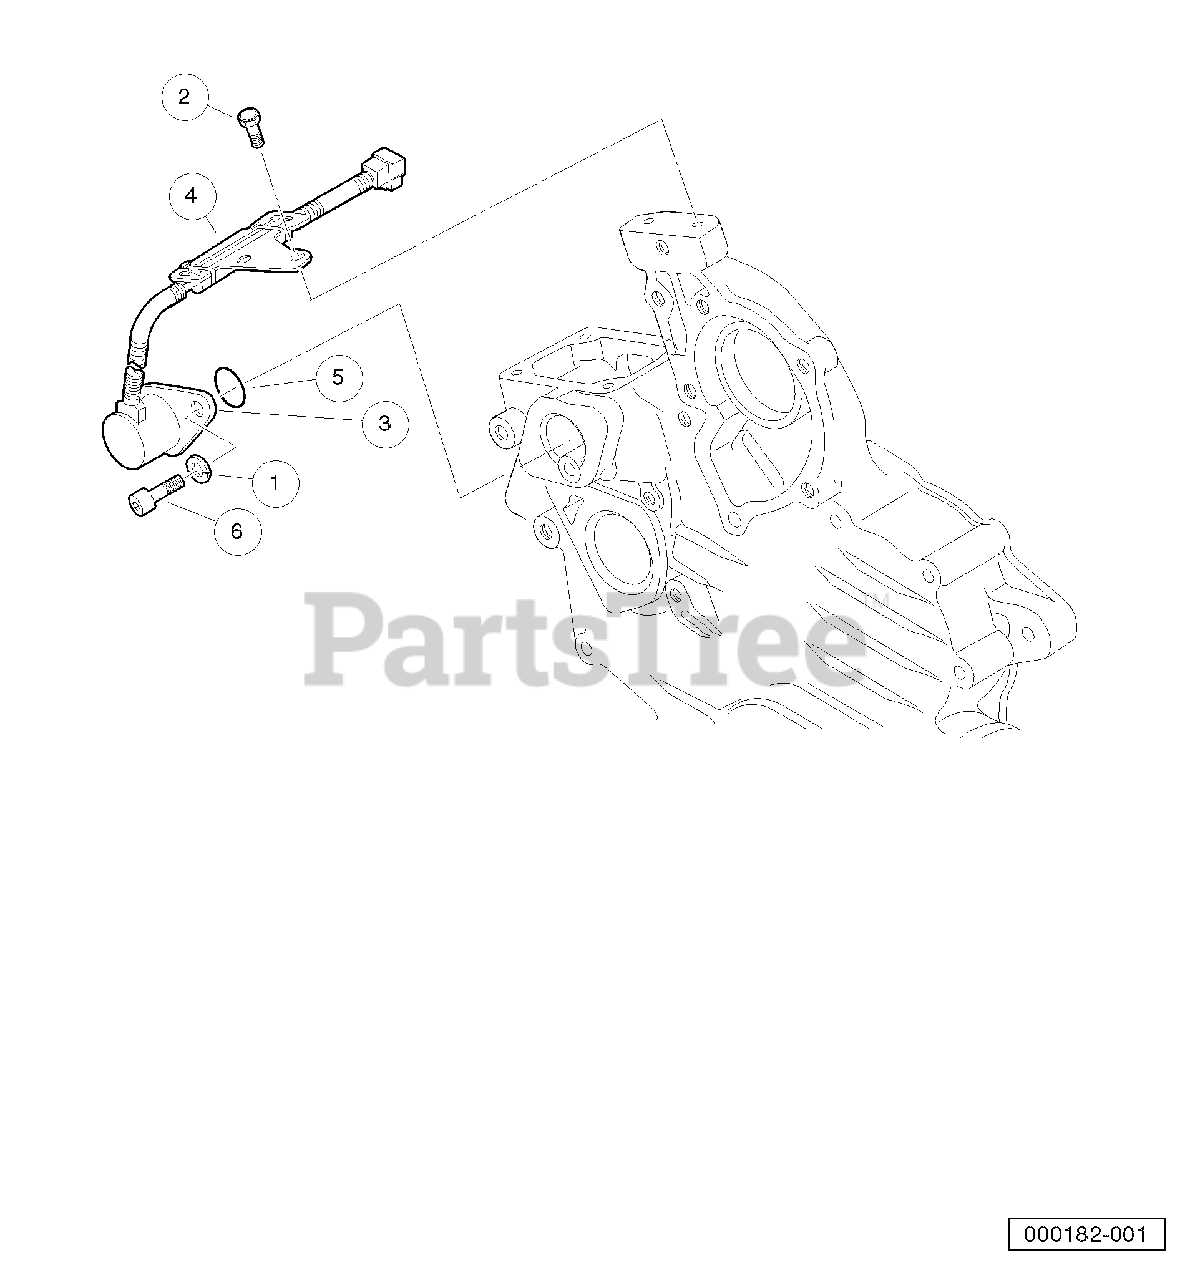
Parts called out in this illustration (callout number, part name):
1	Washer, Spring, M6, D722
2	Bolt, Solenoid, Stop, D722
3	Solenoid, Stop
4	Stay, Stop Solenoid
5	O-Ring, Stop Solenoid
6	Bolt, Stop Solenoid
